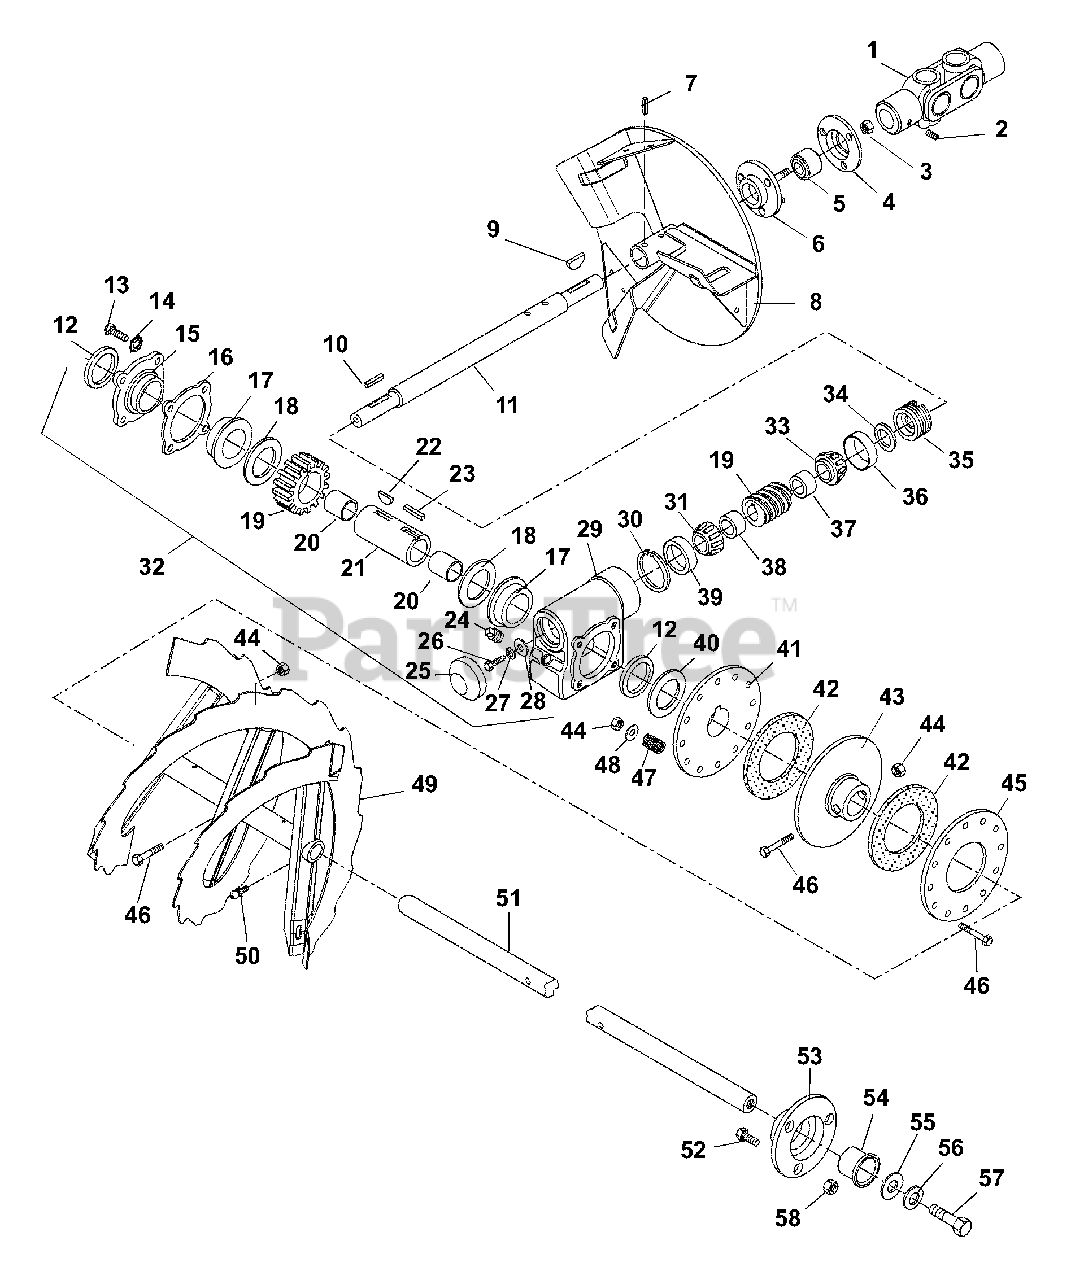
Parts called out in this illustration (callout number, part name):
1	Joint Assembly
2	Screw-Set .38-16 x .38
3	Nut-Locking-Center .250-20
4	Bearing Flange
5	Bearing-Ball 1.0 x 2.0 x .56
6	Bearing Flange
7	Pin-Roll .313 x 1.75
8	Fan, 16"
9	Key-Woodruff .188 x .875 x .375 Hard
10	Key, Square .188 x 1.00 x .188
11	Worm Shaft, 16"
12	Seal 1.625 x 2.125 x .250
13	Bolt-Hex .25-20 x .75 Grade 2
14	Washer-Lock External .250 ID
15	Gearcase Cover
16	Gasket
17	Bushing-Flange 1.625 x 1.87 x 1.68 x 2.250
18	Washer-Flat-Steel 1.625 x 2.500 x .012
19	Worm & Gear Service Assembly
20	Bushing-Sleeve 1.125 x 1.250 x 1.000
21	Gearcase Shaft
22	Key-Feather .25 x .875 x .25
23	Key-Square .25 x .625 x .375
24	Pipe Plug
25	Dust Cap
26	Bolt-Hex .31-18X.75 Grade 5
27	Washer-Locking .31 x .078
28	Washer-Flat-Steel .344 x .688 x .065
29	Gearcase
30	Ring-Retaining-Internal 1.781 x .062
31	Bearing-Cone .750 x .61
32	Gearcase Assembly
33	Bearing-Cone 1.0 x .58
34	Seal 1.125 x 1.375 x .125
35	Adjustment Plug
36	Bearing-Cup 1.980 x .420
37	Bearing Spacer
38	Bearing Spacer 1.12 x 1.52 x .5
39	Bearing-Cup 1.78 x .475
40	Washer-Flat-Steel 1.625 x 2.500 x .060
41	Driver
42	Friction Disc
43	Driven Plate
44	Nut-Lock-Center .31-18
45	Pressure Plate
46	Bolt-Hex .31-18 x 2.00 Grade 5
47	Spring-Compression .156 x .665 x .75
48	Washer-Flat-Steel .323 x .625 x .062
49	32" Right Side Rake
49	32" Left Side Rake
50	Fitting-Lube .25-28 x .256
51	32" Rake Shaft
52	Bolt-Serrated Neck Slotted .25-20 x .50
53	Bearing, Support
54	Bushing-Flange 1.000 x 1.12 x .62 x 1.50
55	Washer-Flat-Steel .511 x 1.441 x .125
56	Washer-Lock .500 x .151
57	Bolt-Hex .50-13 x 1 Grade 5
58	Nut-Locking-Flange .250-20
